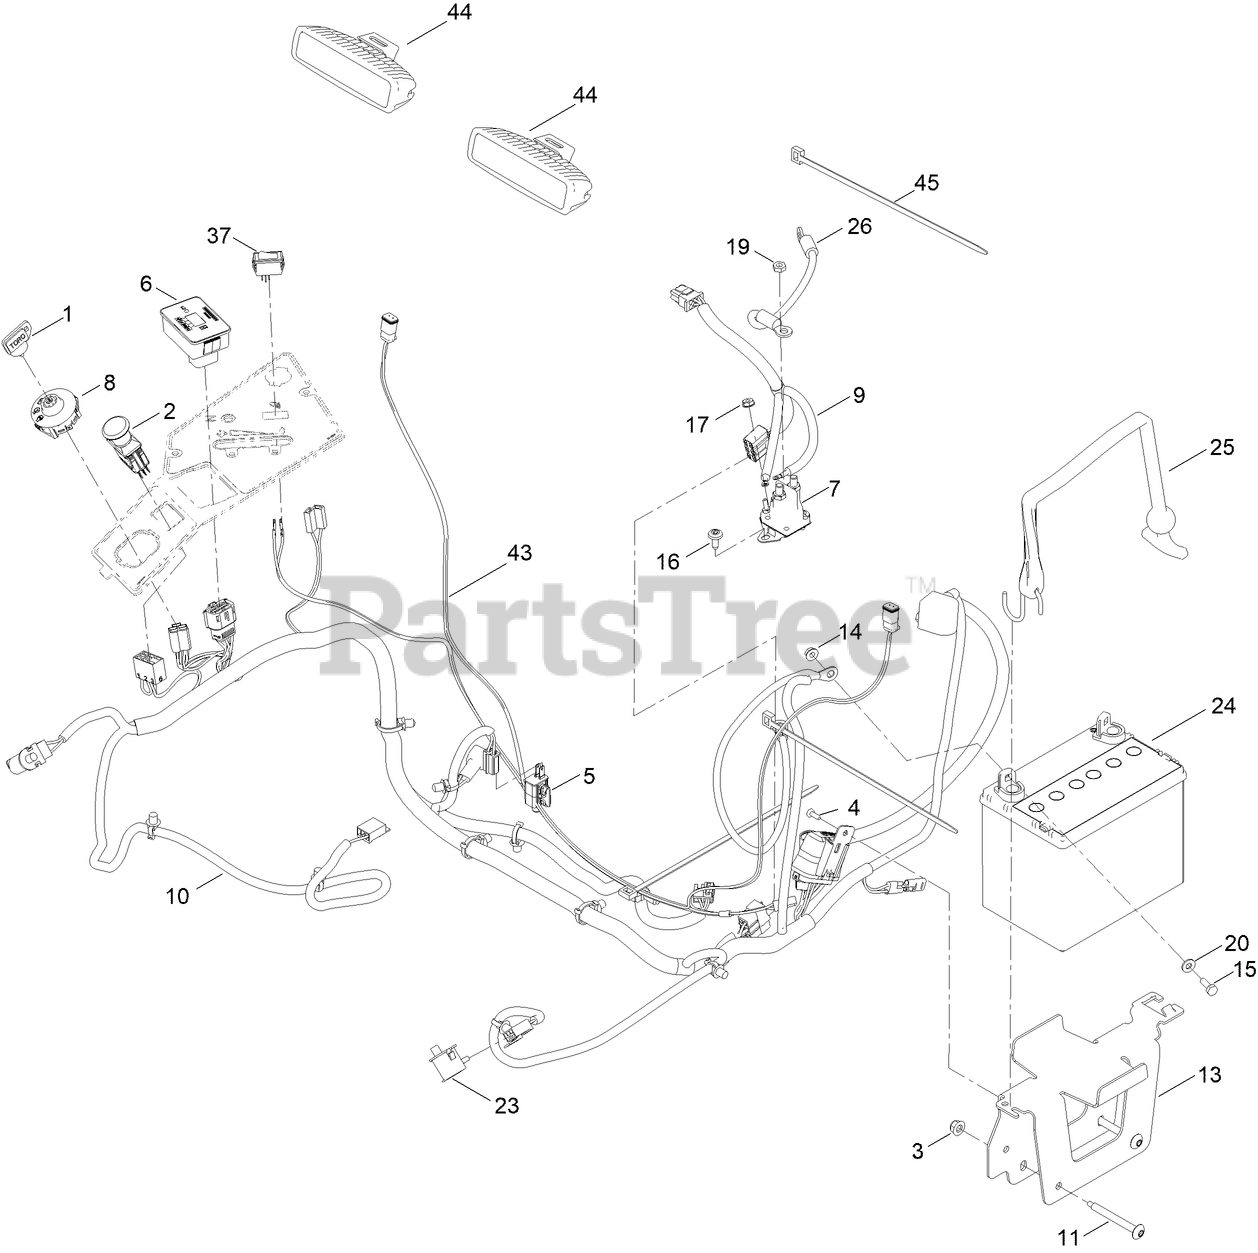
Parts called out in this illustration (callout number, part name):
1	KEY-IGNITION
2	SWITCH-PTO
3	NUT-HF, NI
4	SCREW-FORMING, THREAD
5	SWITCH
6	MODULE ASM
7	SOLENOID
8	SWITCH-IGNITION
9	ADAPTER-HARNESS, WIRE
10	HARNESS-WIRE
11	SCREW-TORX
13	TRAY-BATTERY
14	NUT-HF
15	SCREW-HH
16	SCREW-TORX
17	NUT-KEPS
19	NUT-JAM
20	WASHER-FLAT
23	SWITCH-BAIL
24	BATTERY- WET, 12V, 300 CCA
25	STRAP, BUNGEE
26	CABLE-BATTERY, POSITIVE
37	SWITCH-ROCKER
43	HARNESS-WIRE, LIGHT KIT
44	LIGHT-LED
45	TIE-PLASTIC
